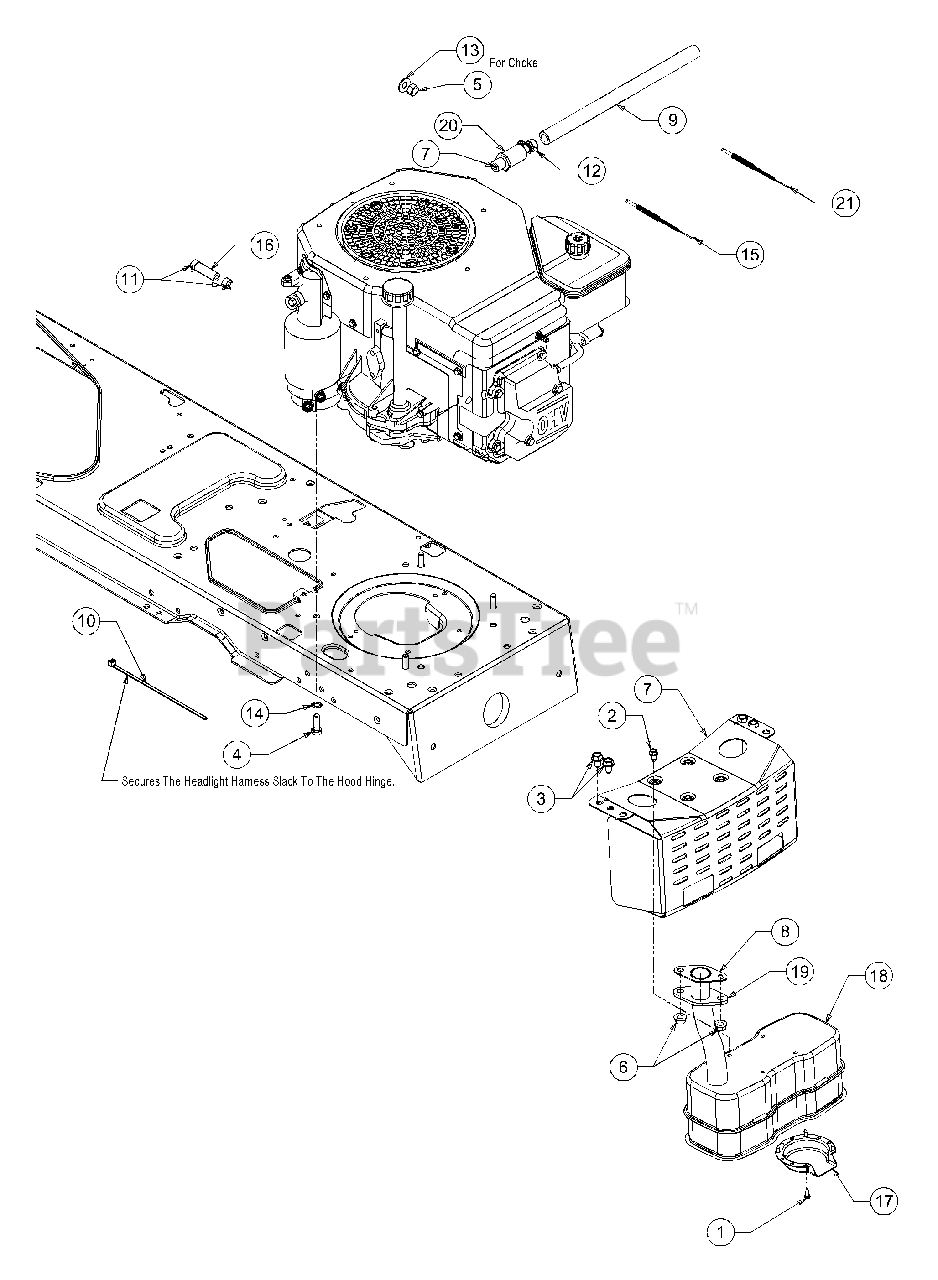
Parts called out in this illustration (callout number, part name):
1	Screw, #8-18, 0.500
2	Screw, Self-tapping, 1/4-20, 0.500
3	Screw, 5/16-12, 0.75
4	Screw, M8-1.25, 25.0, Gr. 8
5	Nut, Hex, 3/8-16, Gr. 8
6	Flange Nut, M8, 1.25-6h
8	Gasket, Exhaust, Kohler Single
9	Hose, Extension, Oil Drain
10	Cable, Tie, 3/16 x .05 x 7.4
11	Clamp, Hose, .490 Dia.
12	Cap, Oil, Drain
13	Washer, Flat, .406 x .875 x .059
14	Washer, External Lock, 5/16
15	Cable, Throttle, 27.4 Lg
16	Hose, 10' Fuel Line
17	Deflector, Muffler
18	Muffler, Single Inlet
19	Pipe, Exhaust, Kohler Single
20	Drain, Oil
21	Choke Control
